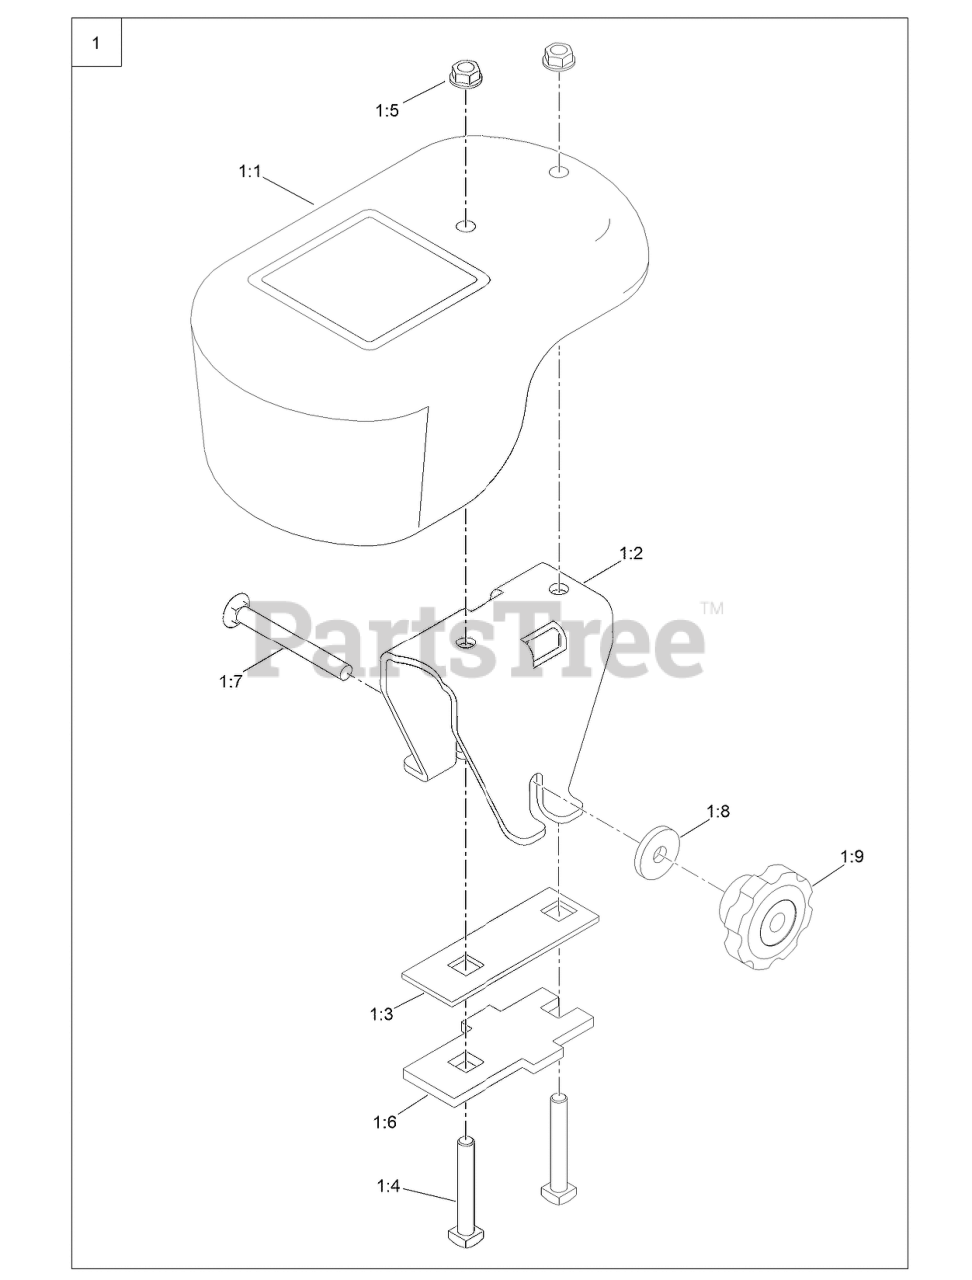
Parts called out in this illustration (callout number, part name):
1	CASTER WEIGHT ASM
1:1	WEIGHT WITH DECAL ASM
1:2	CHANNEL-MOUNT, WEIGHT
1:3	PLATE-BRACKET, WEIGHT
1:4	BOLT-SQH
1:5	NUT-HHF, WHIZ
1:6	PLATE-BRACKET, WEIGHT
1:7	SCREW-CARR
1:8	WASHER-BACKUP
